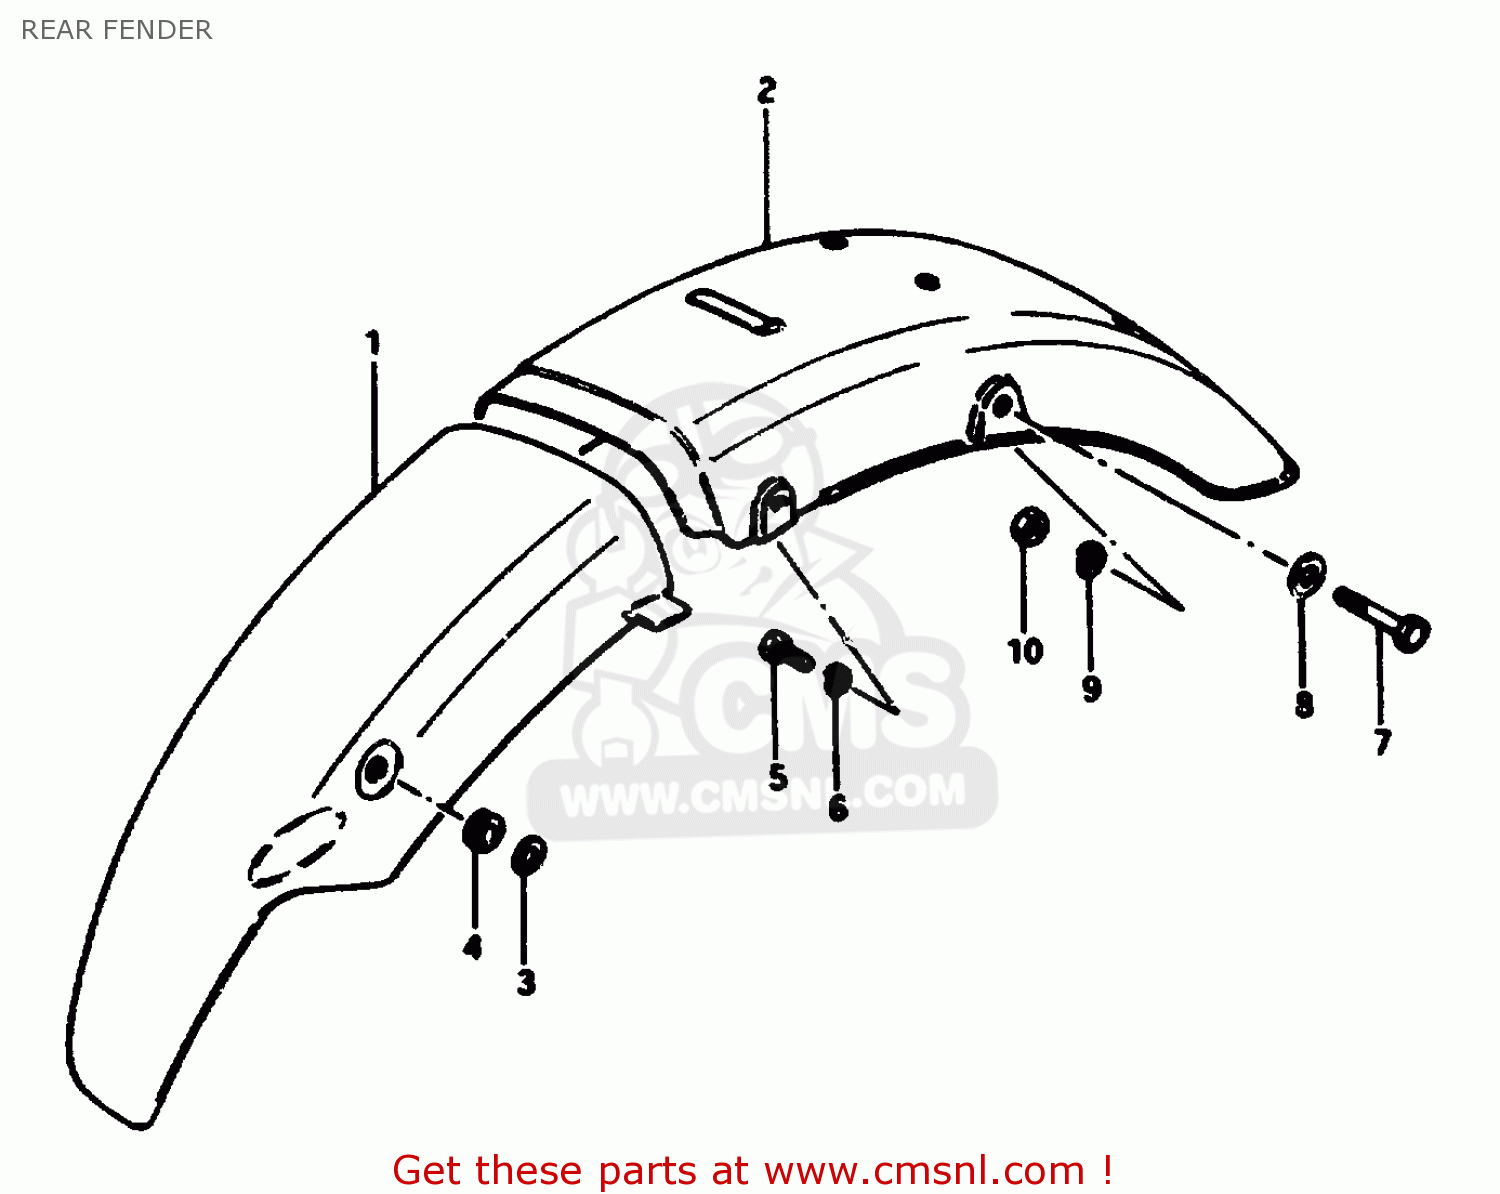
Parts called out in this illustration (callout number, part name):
1	BODY, REAR FENDER FRONT
2	FENDER, REAR
3	WASHER
4	CUSHION
5	BOLT
6	LOCK WASHER
7	BOLT
8	WASHER
9	LOCK WASHER
10	NUT
